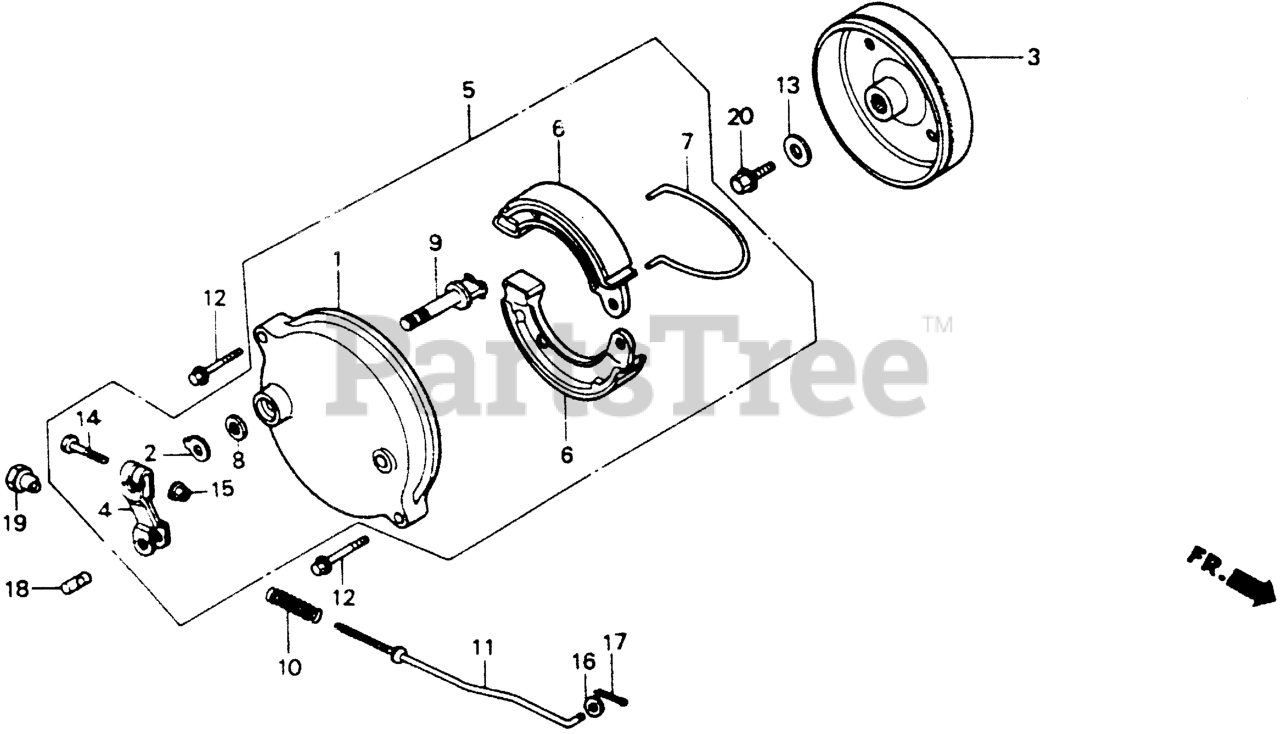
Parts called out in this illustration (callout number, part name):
1	PANEL, BRAKE
2	INDICATOR, BRAKE
3	DRUM, BRAKE
4	ARM, RR. BRAKE
5	PANEL ASSY., BRAKE
6	SHOE, FR. BRAKE (NIPPON) (NOT AVAILABLE)
7	SPRING, BRAKE SHOE
8	SEAL, BRAKE CAM
9	CAM, FR. BRAKE
10	SPRING A, BRAKE ROD
11	ROD C, FOOT BRAKE
12	BOLT, FLANGE (6X28) (CT200) Use up to Engine SN 1530314.
13	WASHER, SPECIAL (28X8.5X4.0)
14	BOLT, HEX. (5X25) (SOURCE: VINTAGE PARTS INC.)
15	NUT, FLANGE (5MM)
16	WASHER, PLAIN (5MM)
17	PIN, COTTER (2.0X15)
18	JOINT A, BRAKE ARM
19	NUT A, BRAKE ROD ADJUSTING
20	BOLT, FLANGE (8X20)
